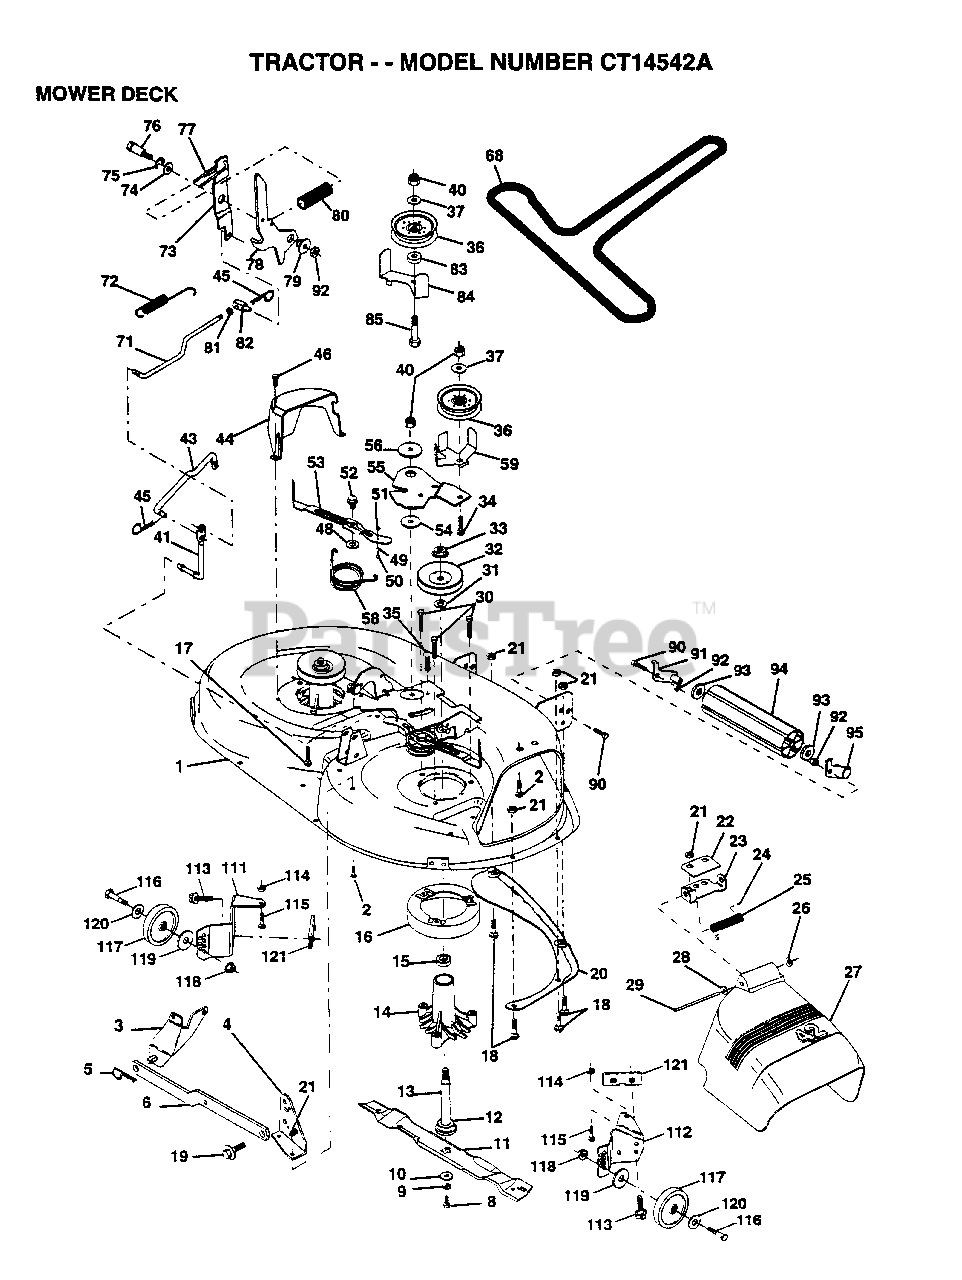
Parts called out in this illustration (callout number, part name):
1	DECK.WELD.42.
2	BOLT
3	BRKT ASM SWAY BAR
4	BRKT DECK SW BAR
8	BLADE BOLT
10	WASHER.HARD.BLADE
11	"BLADE.42"" HIPERF"
12	BEARING.BALL
14	HSG ASM MANDREL
15	BEARING
16	STRIPPER RND MWR
17	BOLT RDHD 3/8-16
18	BOLT
19	BOLT SHD 5/16-18
22	STIFFENER BRKT
23	DEFLECTOR BRKT
24	CAP-SLEEVE LT
25	SPRING TORSION
26	NUT PUSH M
27	DEFLECTOR.SHIELD
28	WASHER
29	HINGE ROD
31	WASHER
34	BOLT
35	XMAS TREE FASTNER
36	FLAT IDLER PULLEY
37	WASHER
41	PIVOT ROD
43	ROD CLUTCH W/NIBS
44	GUARD MAND LH BLK
45	RETAINER M
46	SCREW.1/4-20X5/8
48	HARD SMALL WASHER
50	SHOULDER BOLT
51	LOCKNUT
52	BOLT.SHLD.5/16-18
53	BRAKE PAD ARM ASM
54	HARDENED WASHER
56	SPACER RETAINER
57	KEEPER BELT LH 42
58	SPRING TORSN BRAK
59	GUARD IDLER TUV
68	BELT.V.T-PATH
71	ROD CLUTCH 38/42
72	SPRING.EXT.RETURN
73	CLUTCH ARM SECOND
74	WASHER
75	RING
76	SHOULDER BOLT
77	SPRING KEEPER
79	BUSHING
81	NUT
82	TRUNION ADJ
83	WASHER
85	BOLT
90	BOLT
93	WASHER
113	SCREW
116	BOLT M
117	WHEEL.GAGE.BLK.PL
118	LOCKNUT
119	WASHER
120	WASHER
121	BRACKET.EXTRD.GWL
